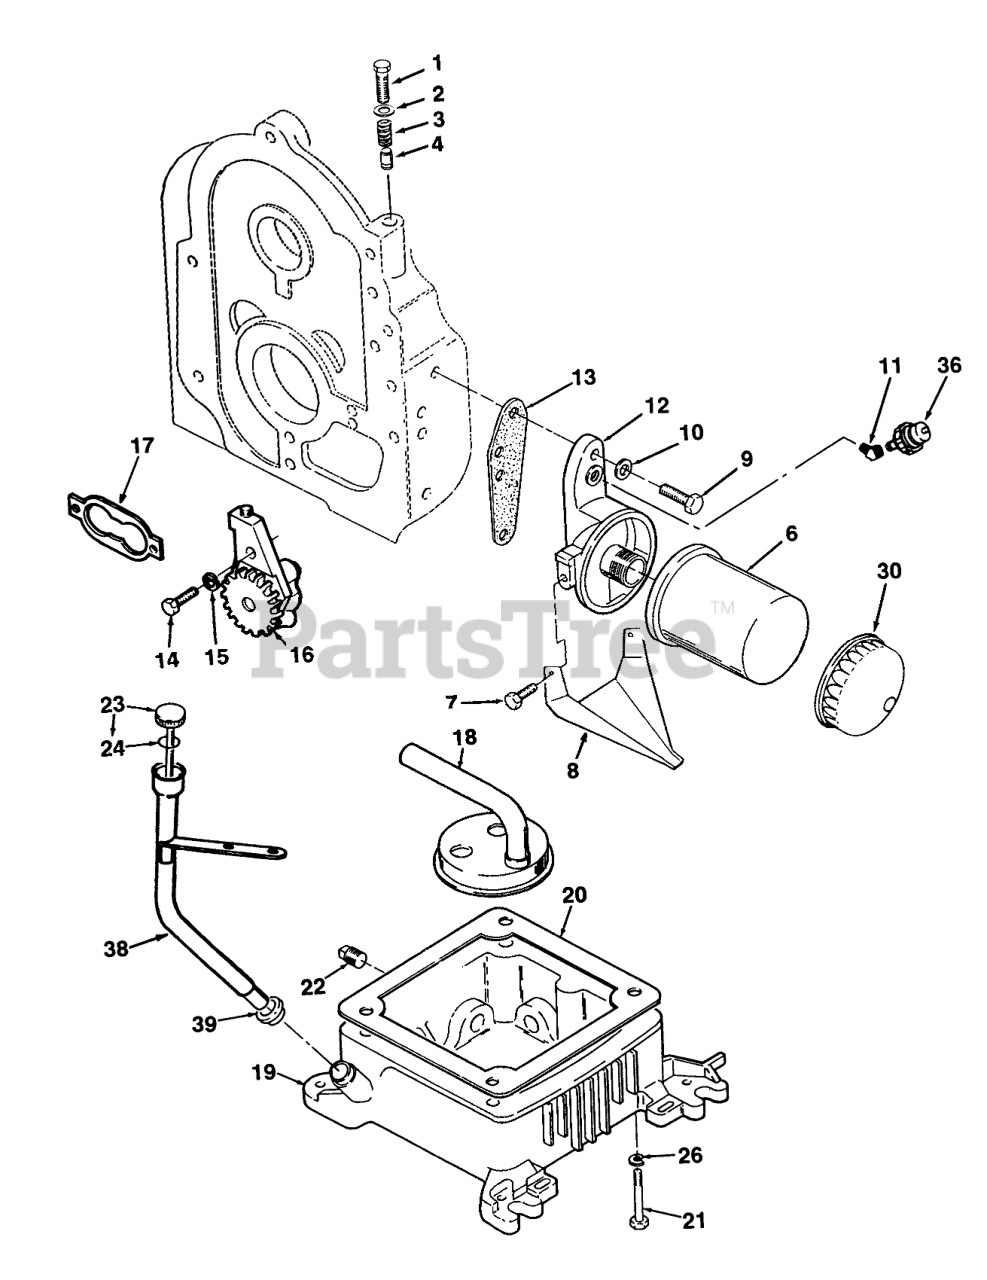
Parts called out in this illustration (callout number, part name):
1	Bolt
2	Washer
3	Spring
4	Piunger
6	OIL FILTER
7	SCREW-HH
8	DRAIN-OIL FILTER
9	HHCS 5/16-18 X 1
10	WASHER
11	ELBOW-45 DEG
12	ADAPTER-OIL FILTER
13	GASKET-OIL FILTER ADAPT
14	SCREW - CAP HEX HEAD
15	WASHER-FLAT
17	Oil Pump Gasket Kit
18	CUP-INTAKE, OIL PUMP
19	Base-Oil (Incl. Plugs & Gasket) Spec. D Engine
20	GASKET
21	Screw
23	Oil Fill Cap & Indicator (Incl. O-Ring)
24	SEAL 0-RING
26	WASHER-FLAT
30	WRENCH-OIL FILTER
36	OIL-PRESSURE SWITCH
38	Oil Fill Tube
39	SEAL-OIL FILL TUBE
